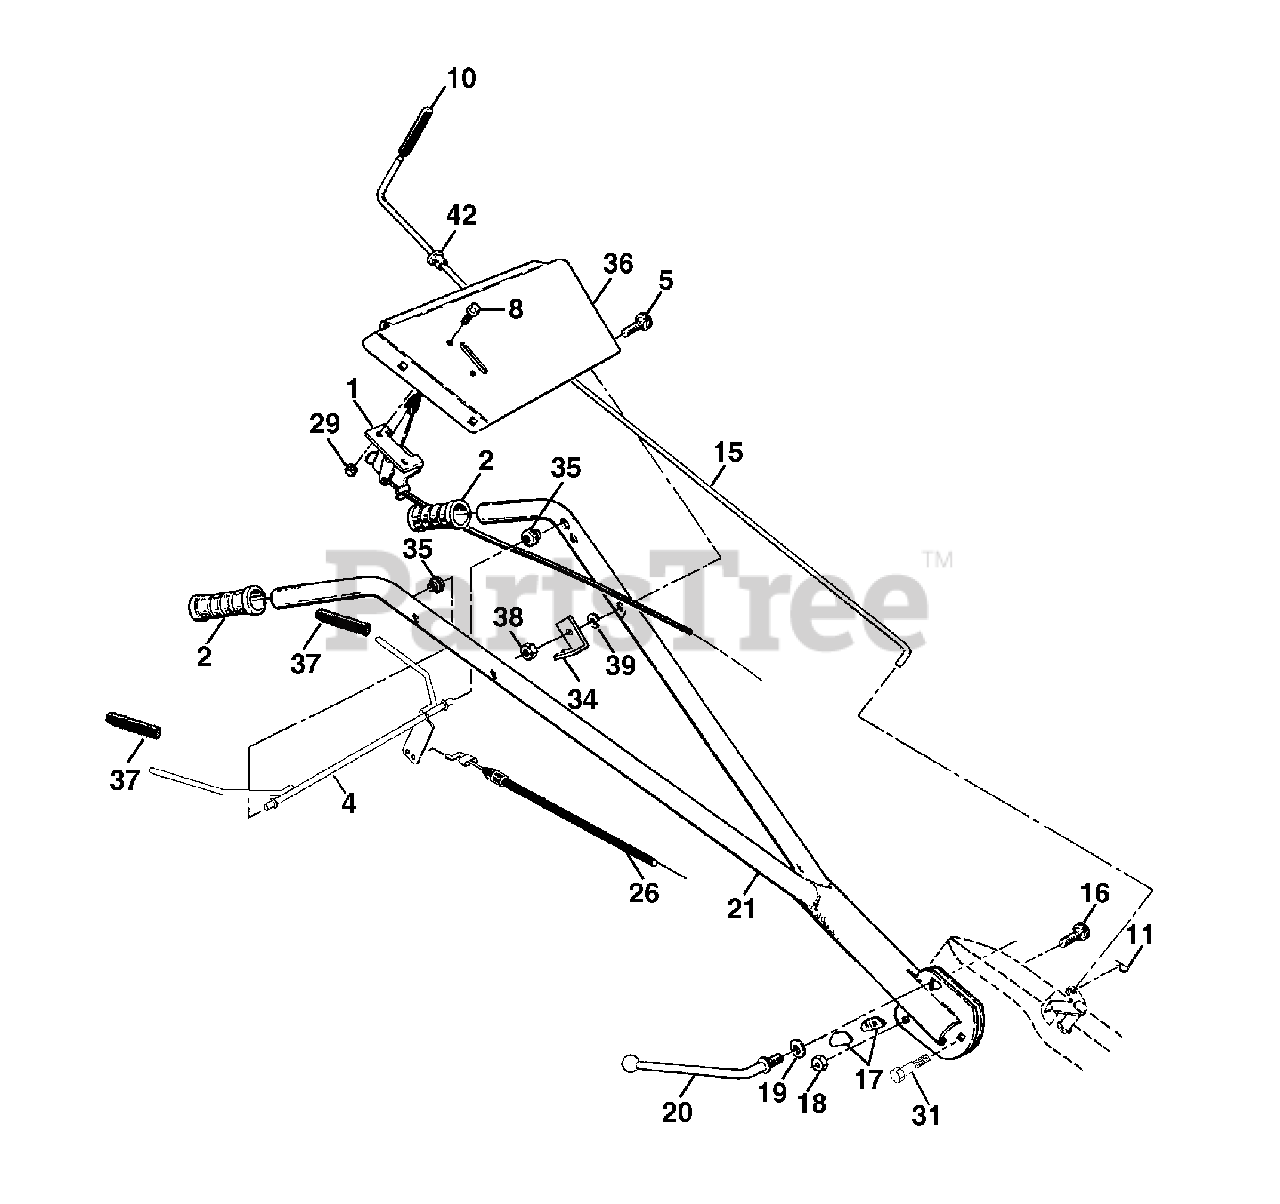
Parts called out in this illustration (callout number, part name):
1	Control, Throttle
2	Grip, Handle
4	Bar, Control
5	Bolt, Carriage 5/16-18 x 1-3/4
8	Screw, Pan Hd. #10-24
10	Grip, Handle
11	Clip, Hairpin
15	Rod, Shift
16	Bolt, Carriage 3/8-16 x 1 Gr. 5
17	Lock, Handle
18	Nut Crownlock 3/8-16 UNC
19	Washer 13/32 x 1 x 11 Ga.
20	Lever, Lock, Handle
26	Cable, Clutch
29	Nut, Keps #10-24 UNC
31	Bolt, Pivot
34	Bracket, Clutch Cable
35	Grommet, Handle
36	Bracket, Handle
37	Grip, Bar Control
38	Locknut 5/16-18
39	Washer, Lock 5/16
42	Bushing, Snap
